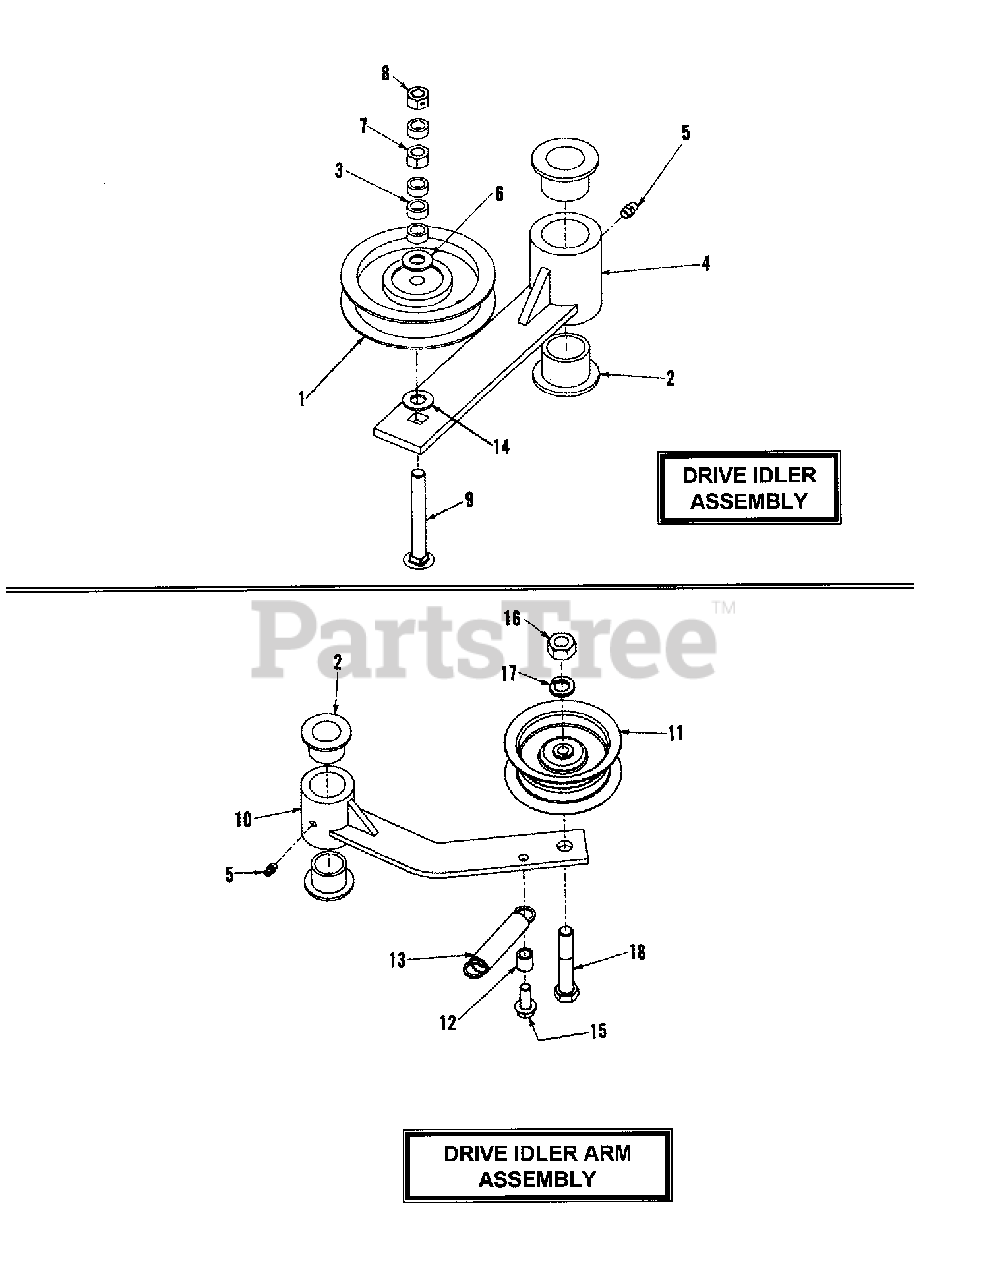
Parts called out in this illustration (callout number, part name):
1	IDLER, 4.12 Flat
2	BUSHING, Caster
3	SPACER, Tie Rod
4	WELDMENT, Idler Arm
5	FITTING, Lube, 1/4-28 Straight
6	WASHER, 3/8" Flat SAE
7	NUT, 3/8-16 Hex , GR5 or B
8	NUT, 3/8-16 Hex Center Lock, GR5 or B
9	BOLT, 3/8-16 x 3" Square Neck Carriage, GR5
10	WELDMENT, Idler Arm- 48" Deck
11	IDLER, 3-1/4 O.D. x 1-3/4" Flat
13	SPRING, Extension
14	WASHER, 3/8" Flat SAE
15	SCREW, 3/8-16 x 1" Hex Washer Self-Tap
16	NUT, 1/2-13 Hex, GR B
17	WASHER, 1/2" Split Lock
18	SCREW, 1/2-13 x 3" Hex Head Cap
